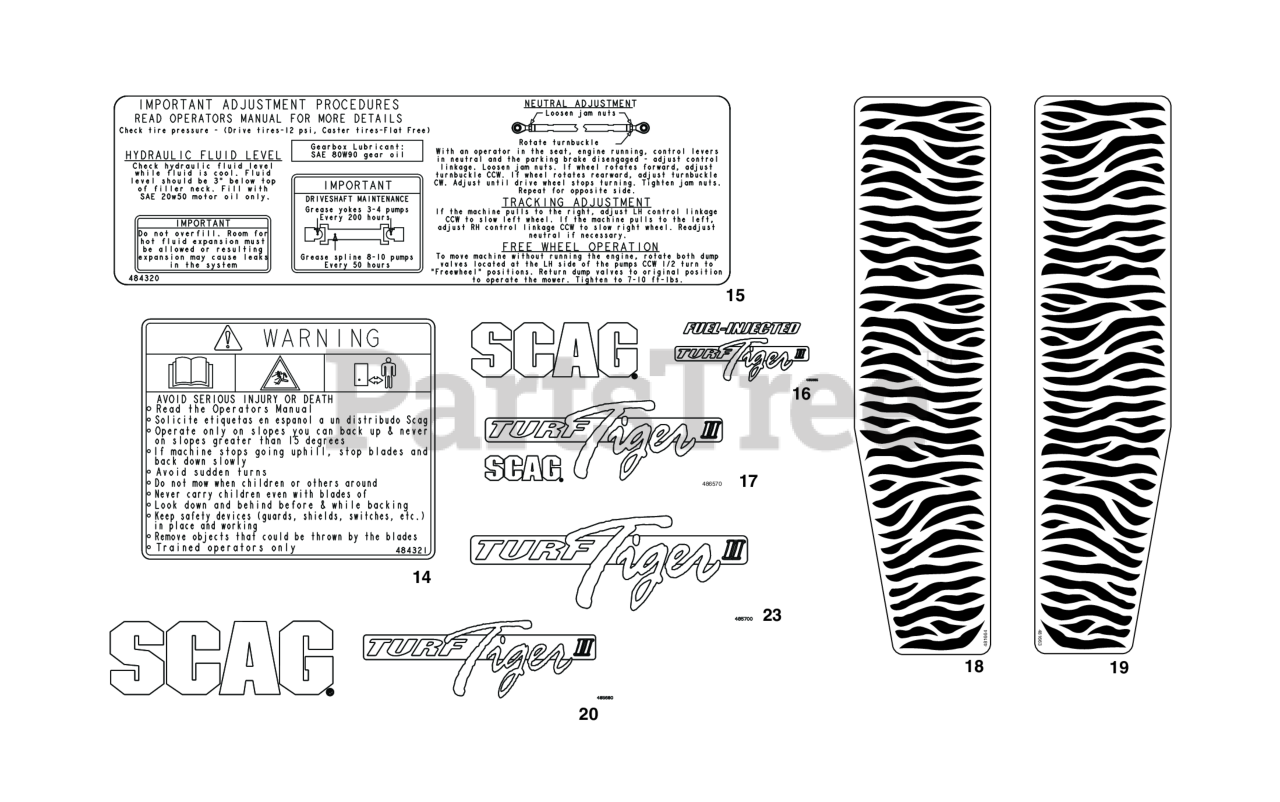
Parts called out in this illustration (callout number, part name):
14	Decal, Start/Drive Procedure
15	Decal, Checks and Adjustments
16	Decal, Hood - STTII Fuel Injected
17	Decal, Turf Tiger II
18	Decal, Stripes-RH
19	Decal, Stripes-LH
20	Decal, Hood - STTII
23	Decal, Turf Tiger II
